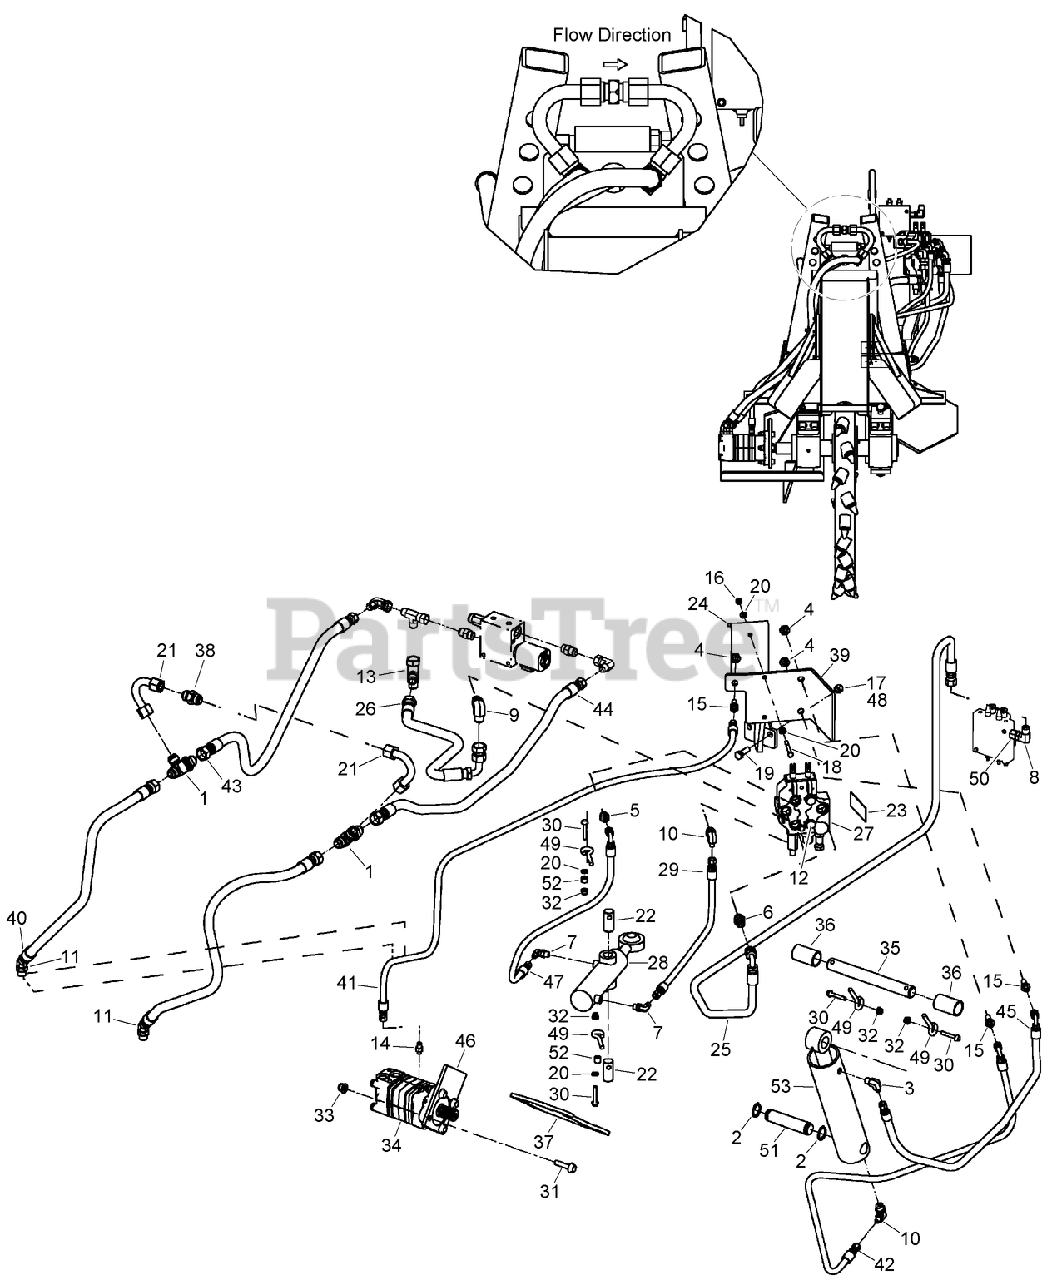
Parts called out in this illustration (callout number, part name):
1	TEE - Bulkhead Adapter
2	RING-RETAINING
3	ELBOW - 90, 37FL 3/8 Tube x 3/8 NPFT
4	NUT-LOCK, BULKHEAD
5	CONNECTOR
6	CONNECTOR-Str Thd 5/8, 37FL-ORB 5/8
7	ELBOW-90 DEG (ADJUSTABLE 37 DEG)
8	ELBOW - 90 Degree, 7/8-14 Flare x 3/4-16 inch Adj O-Ring Boss
9	ELBOW-90 Adj 37FL 3/4 x 5/8 Tube
10	ELBOW-90 Adj 37FL, 3/8 x 1/2 Tube
11	FITTING-ELBOW-45 DEG
12	PLUG-HEX HD
13	FITTING-TEE
14	ADAPTER-STRAIGHT
15	UNION-BULKHEAD
16	NUT-HEX
17	NUT-HEX
18	BOLT - Hex, 5/16 NC x 2-3/4 inch
19	SCREW-HH
20	WASHER-FLAT
21	TUBE ASM
22	PIN-pivot
23	DECAL-plow control pattern, lift/swing
24	BRACKET - Mounting, Plow Control Valve
25	HOSE - 2135 mm (84 inch) Long, Steering and Attachment Lift Control Valve to Plow Control Valve
26	HOSE - 457 mm (18 inch) Long, Plow Lift / Swing Control Valve to Tee
27	VALVE ASSEMBLY - Control, Plow Lift and Swing
28	CYLINDER ASSEMBLY - 51 (2) ID x 143 mm (5-5/8 inch) Stroke, Plow Swing
29	HOSE - 510 mm (20 inch) Long, Plow Control Valve to Plow Swing Cylinder, Closed End
30	SCREW, METRIC FLANGE w/BODY - M8 x 50
31	SCREW-HHF
32	NUT-TORQUE, PREVAILING
33	NUT-HHF, LOCK
34	MOTOR - Hydraulic
35	PIN - Cylinder
36	SPACER - Pin
37	PLATE - Motor Mount
38	VALVE - Check
39	PLATE - Control Valve
40	HOSE ASSEMBLY - Hydraulic
41	HOSE ASSEMBLY - Hydraulic
42	HOSE ASSEMBLY - Hydraulic
43	HOSE ASSEMBLY - Hydraulic
44	HOSE ASSEMBLY - Hydraulic
45	HOSE ASSEMBLY - Hydraulic
46	PLATE - Motor Cover
47	HOSE ASSEMBLY - Hydraulic
49	PIN-RETAINER
50	VALVE ASSEMBLY - Power Beyond
51	PIN-CLEVIS
52	SPACER-13 mm (1/2 inch) long
53	CYLINDER ASSEMBLY - 76 (3) ID x 203 mm (8 inch) Stroke, Plow Lift
